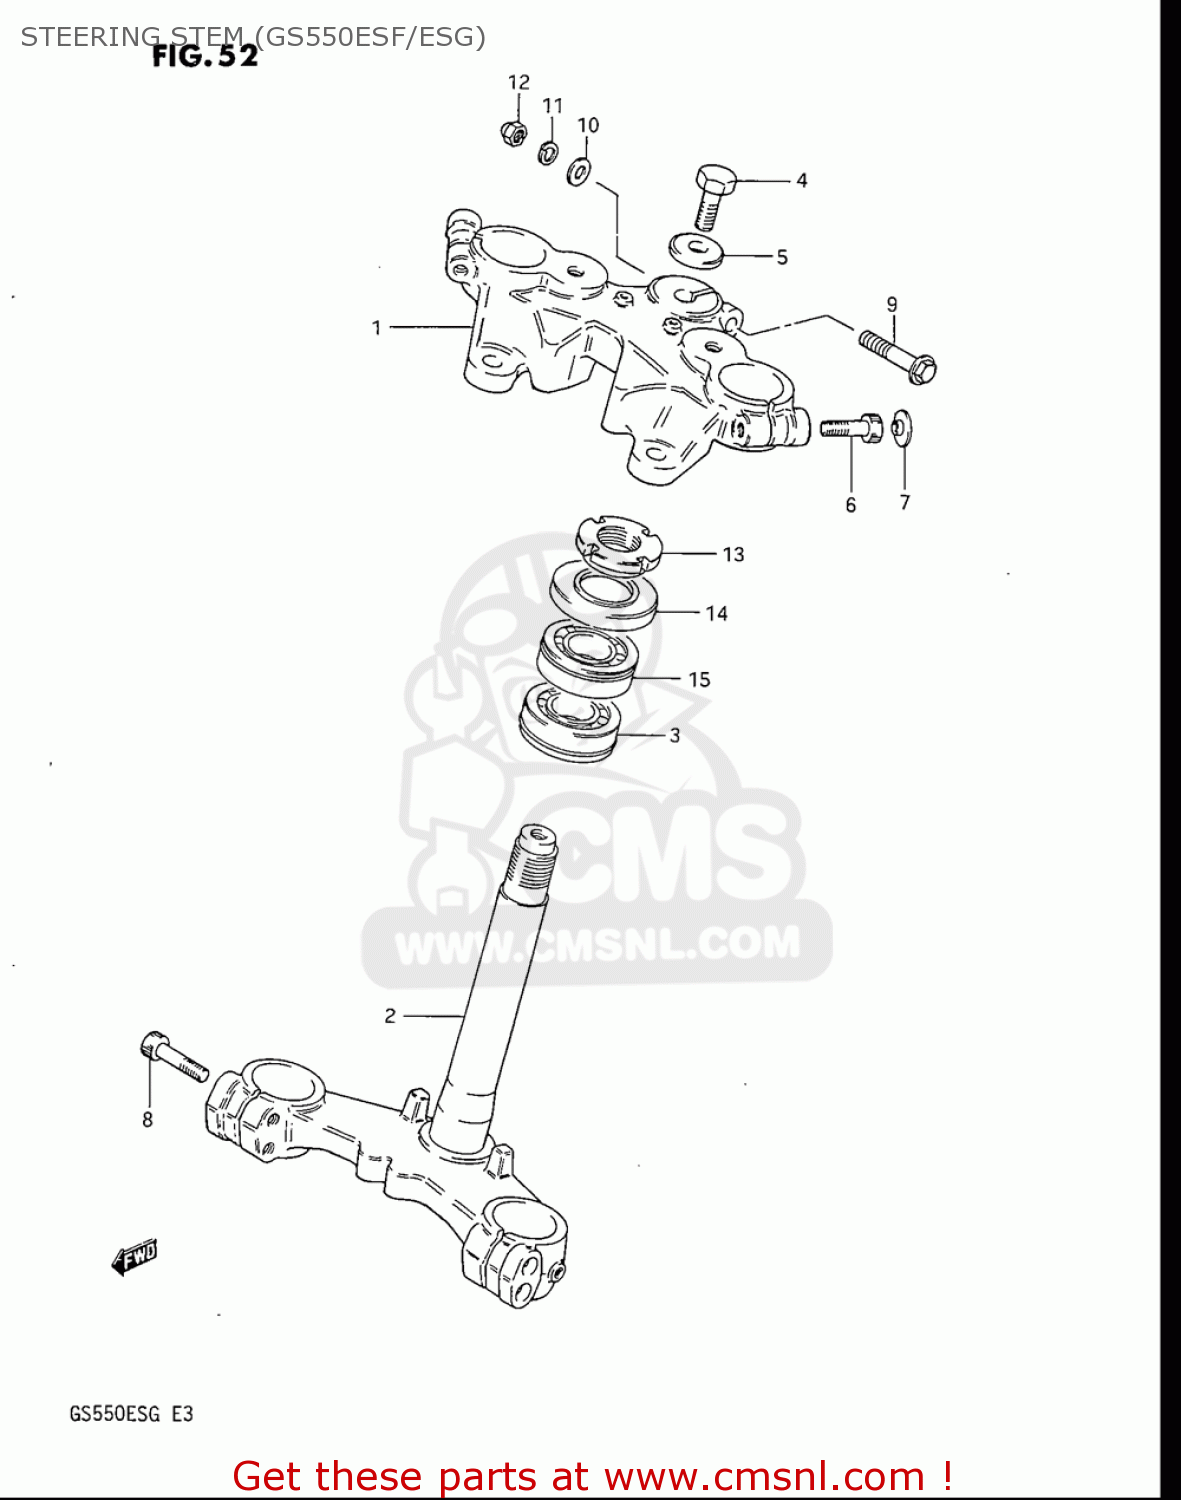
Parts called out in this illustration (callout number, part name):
3	BEARING(30X55X17)
4	BOLT,STEERING STEM HEAD
5	WASHER,STEERING STEM
6	BOLT,FORK INNER TUBE FITTING
7	CAP(OD:20)
8	BOLT
9	BOLT
10	WASHER
11	WASHER,LOCK
12	NUT
13	NUT,STEERING STEM
14	DUST SEAL,STEERING UPR
15	BEARING(25X47X15)
